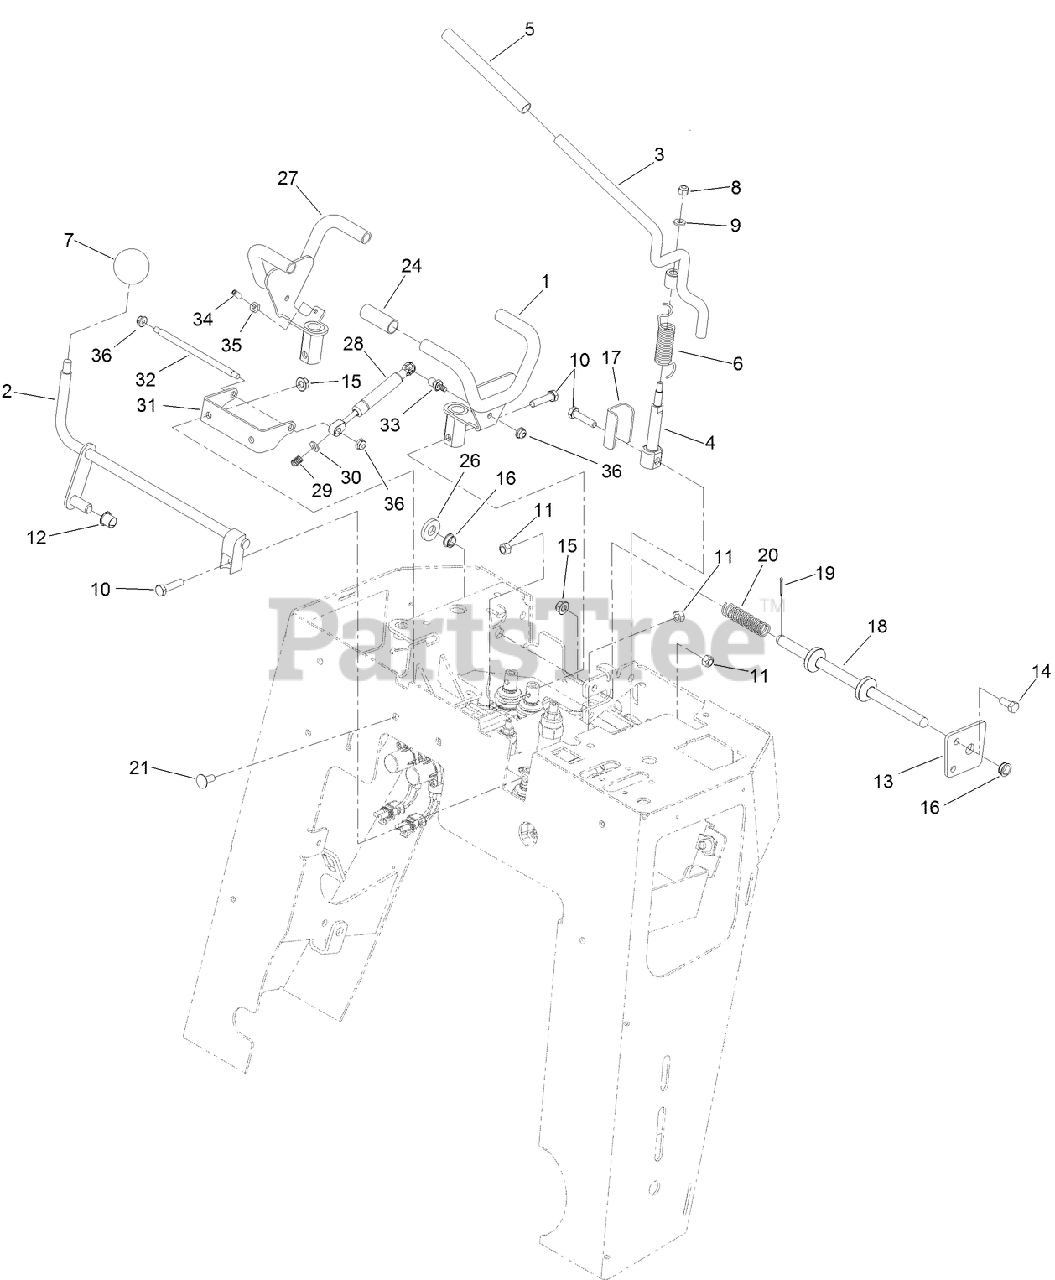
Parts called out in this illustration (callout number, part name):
1	HANDLE-TRACTION, LH
2	LEVER-LIFT
3	AUXILIARY LEVER ASM
4	LEVER-DRIVE, CHAIN
6	SPRING-TORSION
8	NUT-LOCK, NI
9	WASHER-FLAT
10	SCREW-HH
11	NUT-LOCK, NI
12	BUSHING-NYLINER
13	PLATE-BUSHING
14	SCREW-HH
15	NUT-HF, NI
16	BUSHING
17	BRACKET-LEVER
18	ROD-LOCKOUT
19	PIN-COTTER
20	SPRING-COMPRESSION
21	SCREW-CARR
26	WASHER-HARDENED
27	HANDLE-TRACTION, RH
28	DAMPER
29	SPRING-COMPRESSION
30	WASHER-SPCL
31	BRACKET-DAMPER
32	ROD-DAMPER
33	STUD-BALL
34	SCREW-SET, HS
35	NUT-JAM
36	NUT-HF
